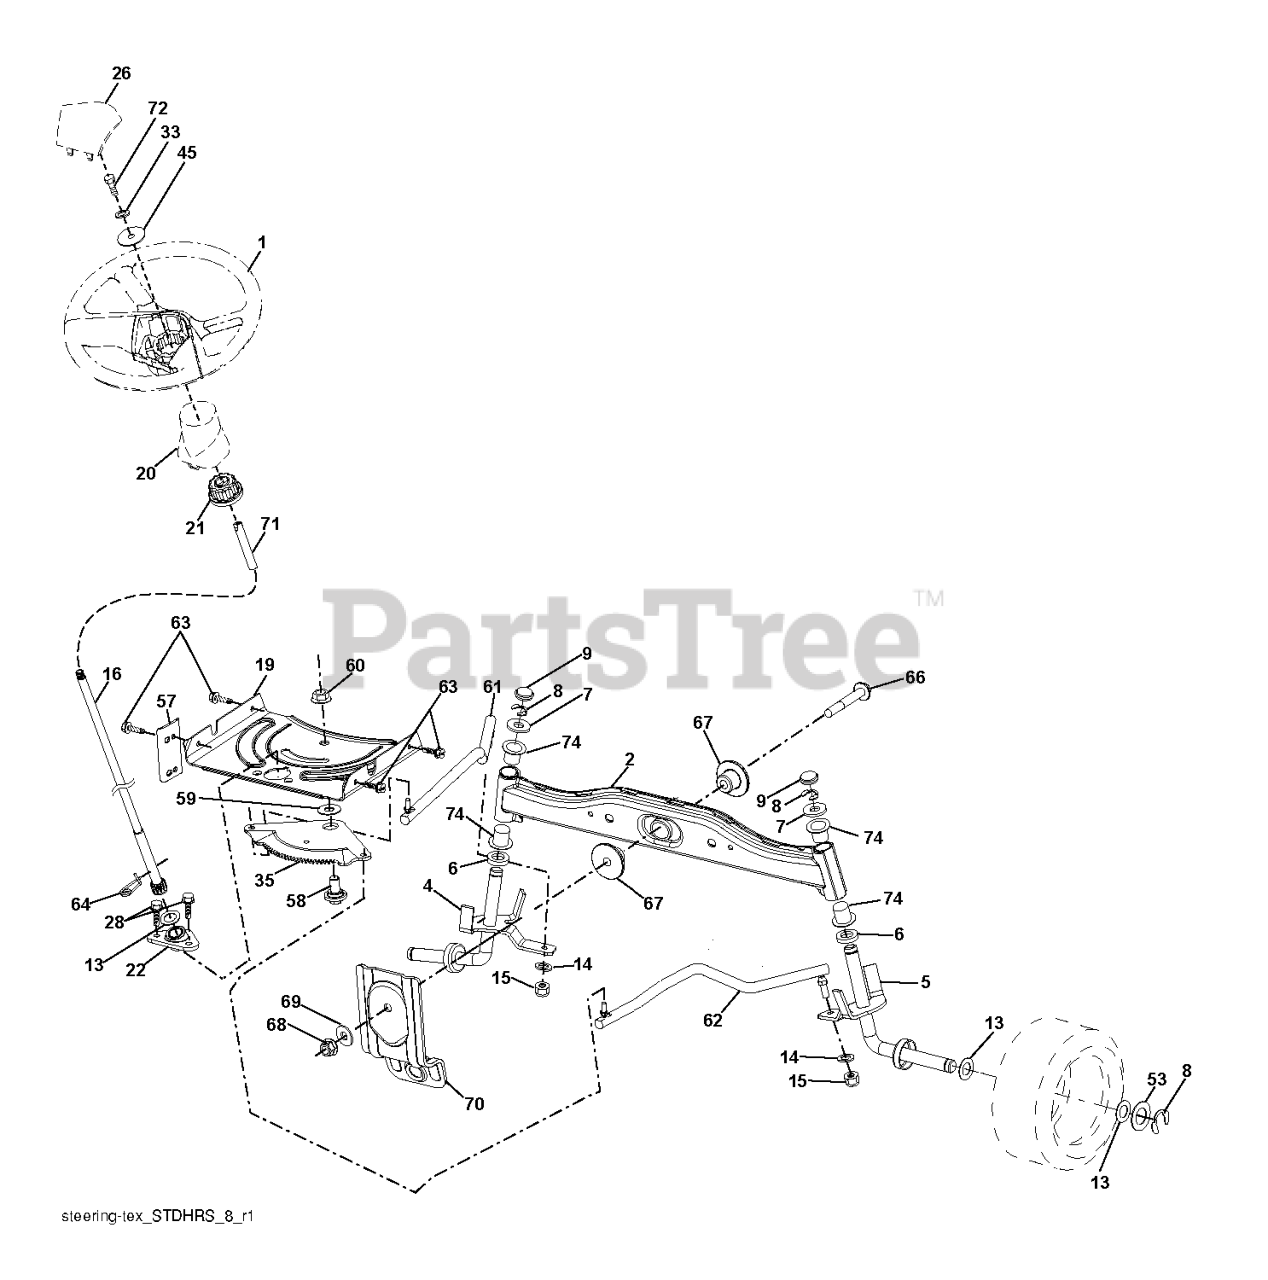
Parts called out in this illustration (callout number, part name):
1	RP WHEEL.STEER.HUSQ.PREM.OVMLD
2	AXLE HALF ASM-WELDED
4	SPINDLE.STEERING.ASM.LH.13".TI
5	SPINDLE.STEERING.ASM.RH.13".TI
6	THRUST WASHER
9	CAP.SPINDLE.BLACK
14	WASHER, LOCK 3/8
15	NUT CROWNLOCK 3/8-24
16	SHAFT.STEER.3/4.PLATED.TEX
19	PLATE.STEER.DDL.NLT/NG
20	BOOT, STEERING
21	ADAPTER, WHEEL STNG..
22	STEERING.SUPT.LOWER.
26	RP INSERT.CAP.WHL.STRG.HUSQ.
28	SCREW, 3/8-16X3/4
33	WASHER.LOCK.HVY.HLCL.SPR.5/16
35	GEAR.SECTOR.PLATE.DDL.
45	WASHER.11/32
53	WASHER.HARDENED
57	BRACKET.UPSTOP.TEX
58	BOLT.SHOULDER.SECTOR.P
59	WASHER.THURST.SECTOR.S
60	NUT FLANGE LOCK 5/8-11
61	DRAGLINK.LH.BALLSTUD.D
62	DRAGLINK.RH.BALLSTUD.D
63	SCREW
64	RETAINER.CLIP.SPRING.S
66	BOLT HEX FGHD 7/16-14 X 3 SERR
67	BUSHING.PM.FRONT AXLE
68	NUT.LOCK.FLANGE.7/16
69	WASHER.1.5X.505X.118
70	BRACKET.SUSP.MWR.FRT.30"SRD
71	SHAFT.EXTEN.STRG.SPLINE
72	BOLT 5/16-18 X 4 W/PATCH
74	BRNG T
